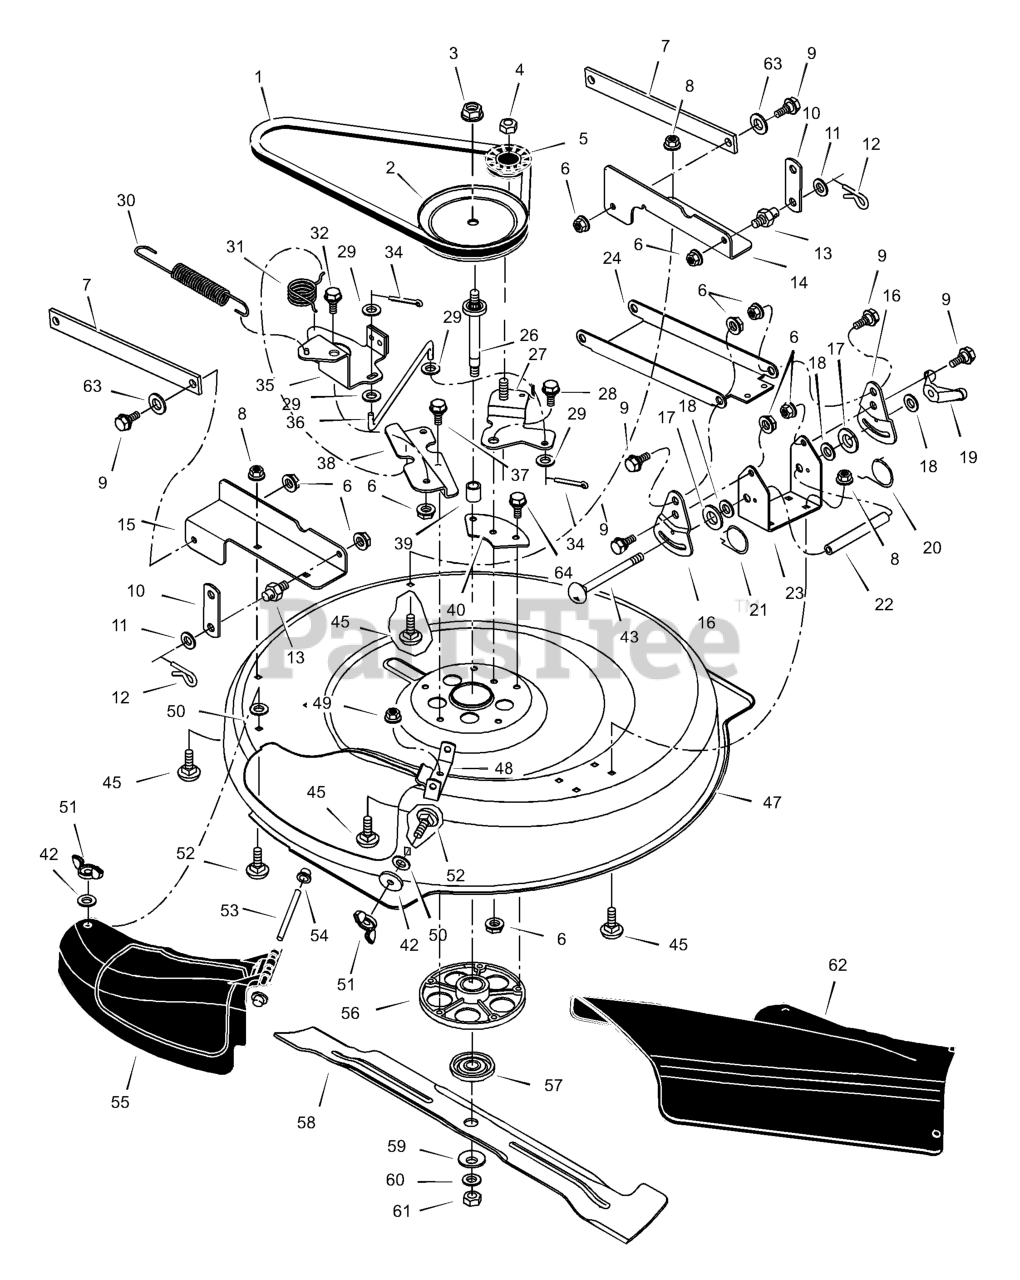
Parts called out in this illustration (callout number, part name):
1	Belt, Blade Drive
2	Pulley, Input
3	Locknut
4	Nut, Flange
5	Pulley, Idler
6	Nut, Flange
7	Arm, Rear
8	Nut, Flange
9	Bolt, Shoulder
10	Link, Lift
11	Washer
12	Pin, Hair
13	Pin, Threaded Shoulder
14	Bracket, Left Rear
15	Bracket, Right Rear
16	Plate, Adjustment
17	Pad, Friction
19	Wingnut
20	Spring, Left Torsion
21	Spring, Right Torsion
22	Tube, Spacer
23	Bracket, Deck
24	Hanger, Front
26	Shaft, Splined
27	Arm Assembly, Idler
28	Bolt, Shoulder
29	Washer
30	Spring, Extension
31	Spring, Torsion
32	Bolt, Shoulder
34	Pin, Cotter
35	Arm Assembly, Brake
36	Link, Idler Arm
37	Bolt
38	Bracket, Brake Mounting
39	Spacer, Jackshaft
40	Plate, Idler Mounting
43	Bolt, Carriage
45	Bolt, Carriage
47	Housing, Blade
48	Hinge, Mulching Cover
49	Nut, Flange
50	Nut, Speed
51	Wingnut
52	Bolt, Carriage
53	Rod, Chute Deflector
54	Cap, Push
55	Cover, Mulch (Black)
56	Mandrel Housing
57	Adapter, Blade
59	Washer, Cup
61	Nut, Blade Mount
62	Deflector, Chute (Black)
63	Bolt, Carriage
64	CAPSCREW, Hex Head, 5/16-18 x 1
